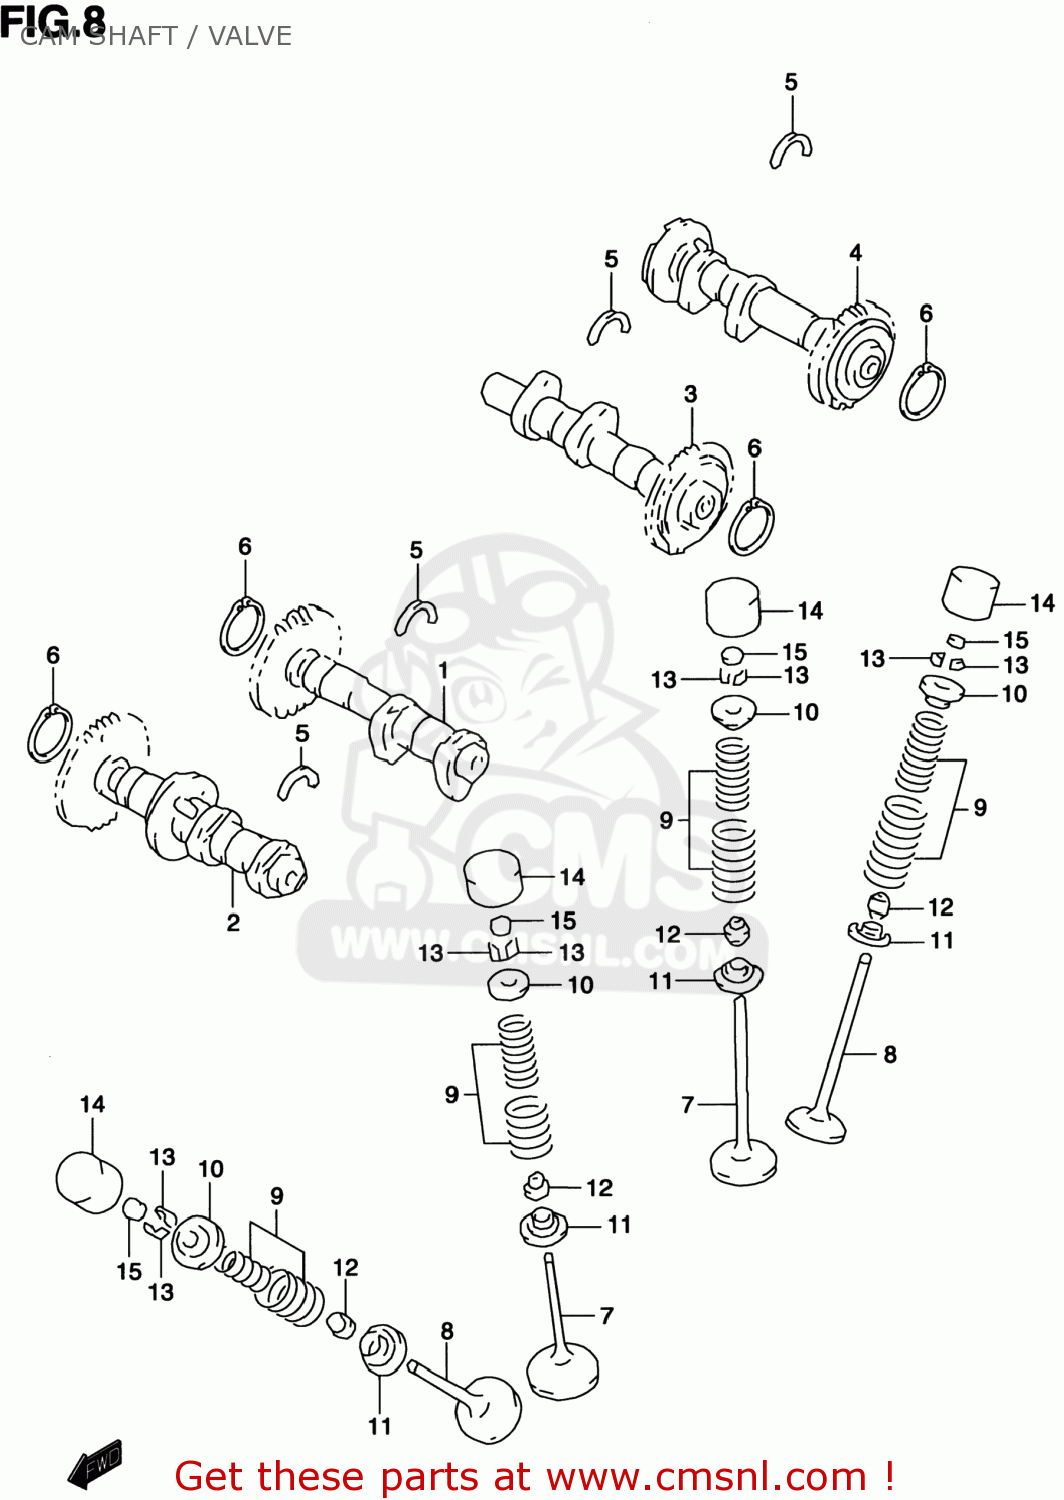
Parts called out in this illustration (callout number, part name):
1	CAMSHAFT ASSEMBLY,INTAKE,FRONT
2	CAMSHAFT ASSY,EXHAUST FR
3	CAMSHAFT ASSY,INTAKE RR
4	CAMSHAFT ASSY,EXHAUST RR
5	C RING
6	CIRCLIP
7	VALVE,INTAKE
8	VALVE,EXHAUST
9	SPRING SET,VALVE
10	RETAINER,VALVE SPRING
11	SEAT,VALVE SPRING
12	SEAL,OIL(5.5X11X8.2)
13	COTTER,VALVE
14	TAPPET
15	SHIM,TAPPET(T:2.3)
16	SHIM SET,TAPPET
17	CASE,TAPPET SHIM
